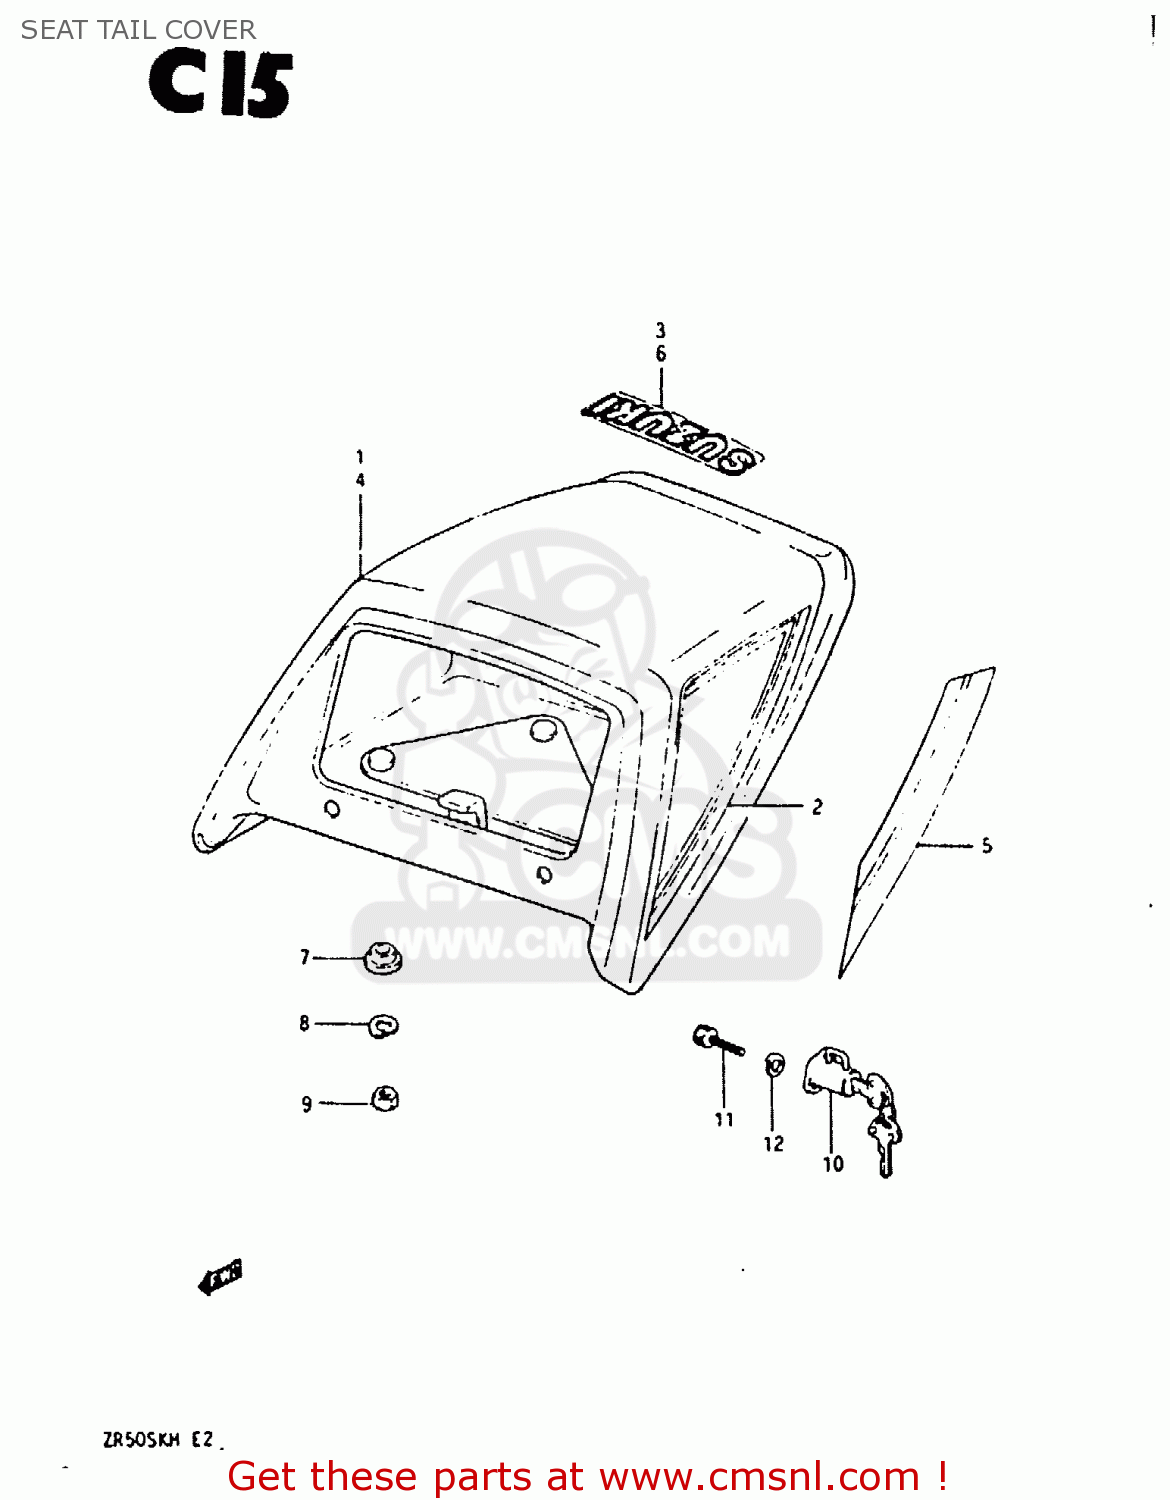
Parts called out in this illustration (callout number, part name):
1	COVER, SEAT TAIL (RED)
2	TAPE SET
3	EMBLEM (WHITE)
4	COVER, SEAT TAIL (BLACK)
5	TAPE SET, SEAT TAIL COVER
6	EMBLEM
7	WASHER
8	WASHER,LOCK
9	NUT
10	LOCK ASSEMBLY,HELMET
11	BOLT 6X11
12	WASHER,LOCK
